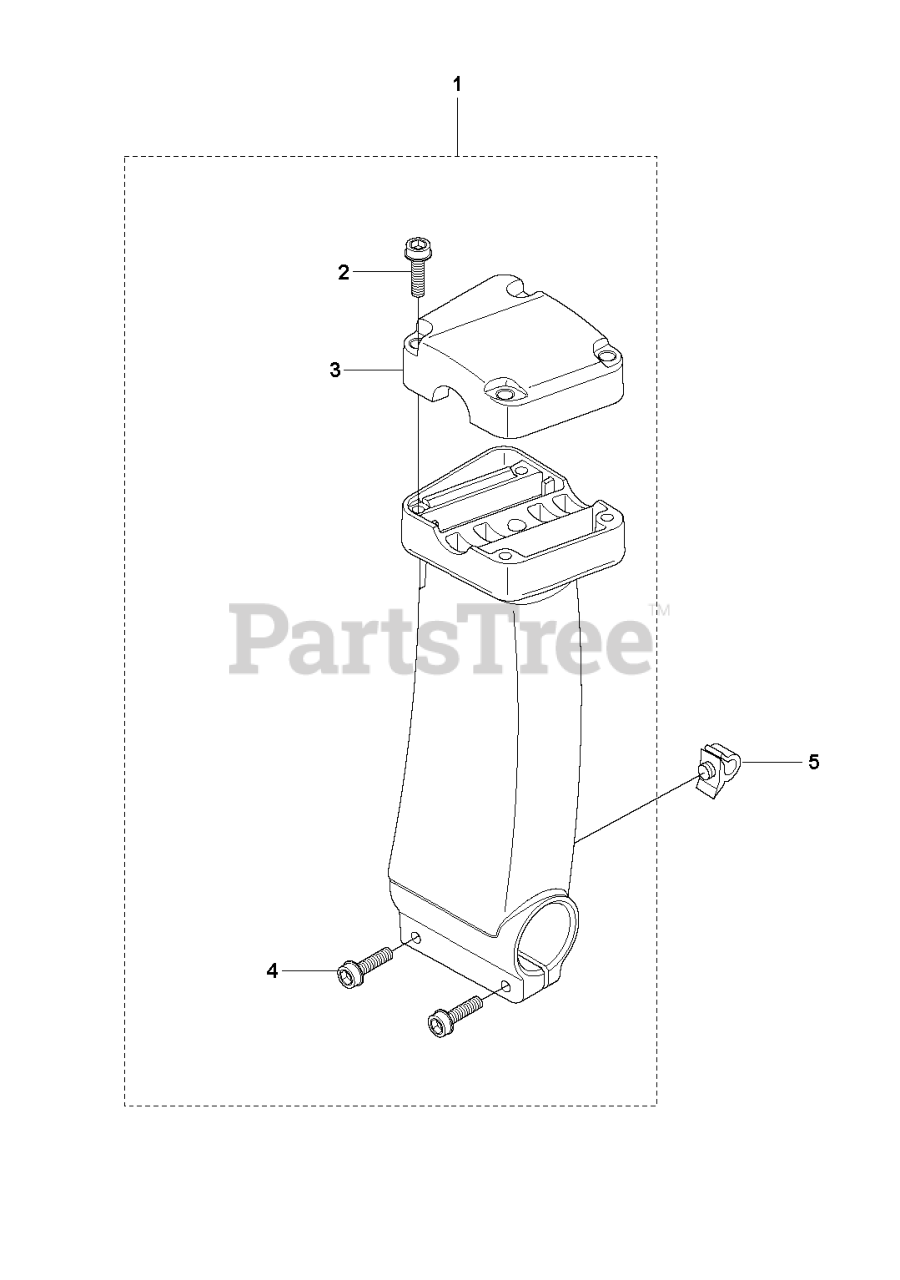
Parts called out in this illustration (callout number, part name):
1	HANDLEBAR BRACKET CPL
3	HANDLEBAR BRACKET
4	SCREW IHSCM
